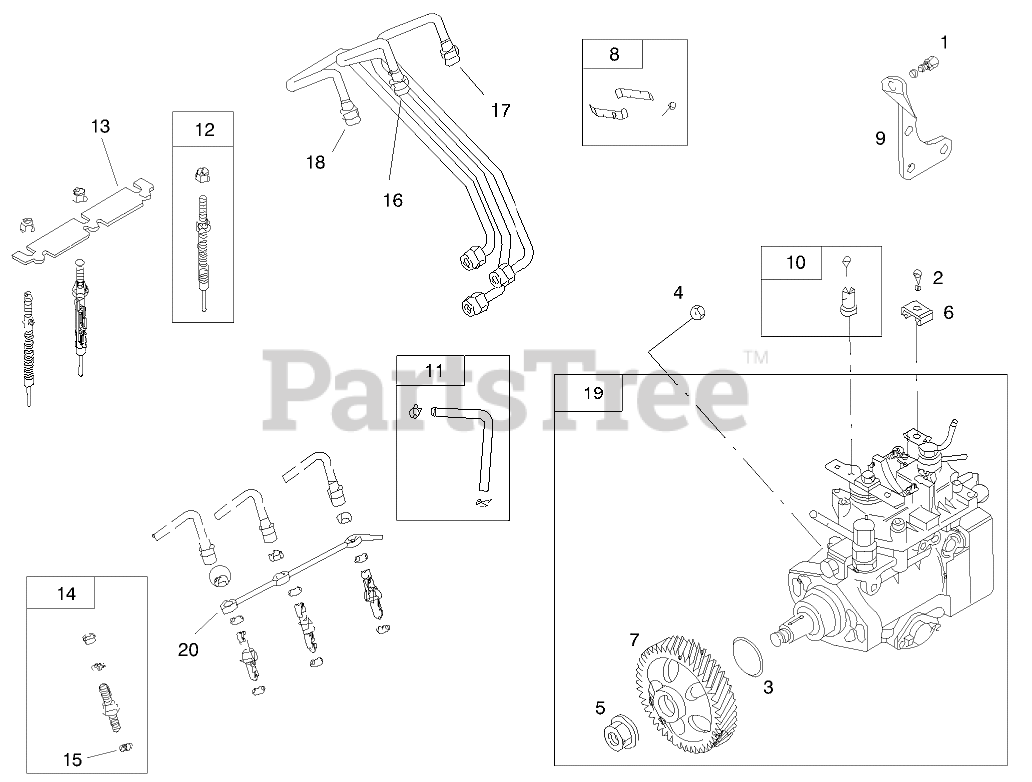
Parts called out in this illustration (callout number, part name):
1	SCREW-HEX
1	HEAD-CYLINDER
2	Screw-Metric
3	O-RING
4	NUT-HEX, METRIC
5	NUT-HEX, METRIC
6	CLAMP-CASING
7	GEAR-DRIVE
8	CLAMP
8	SWITCH-TEMPERATURE, WATER
9	BRACKET-SUPPORT
9	GASKET-SET
10	CLAMP-SWIVEL
11	HOSE / CLAMP ASM
12	PLUG-GLOW
13	STRAP-PLUG, GLOW
14	NOZZLE-INJECTOR
14	KIT-VALVE OVERHAUL
15	SEAT-INJECTOR
15	SHAFT-GEAR
16	PIPE-INJECTOR, NO. 2
17	PIPE-INJECTOR, NO. 3
18	PIPE-INJECTOR, NO. 1
19	PUMP-INJECTION
20	PIPE-RETURN, FUEL
